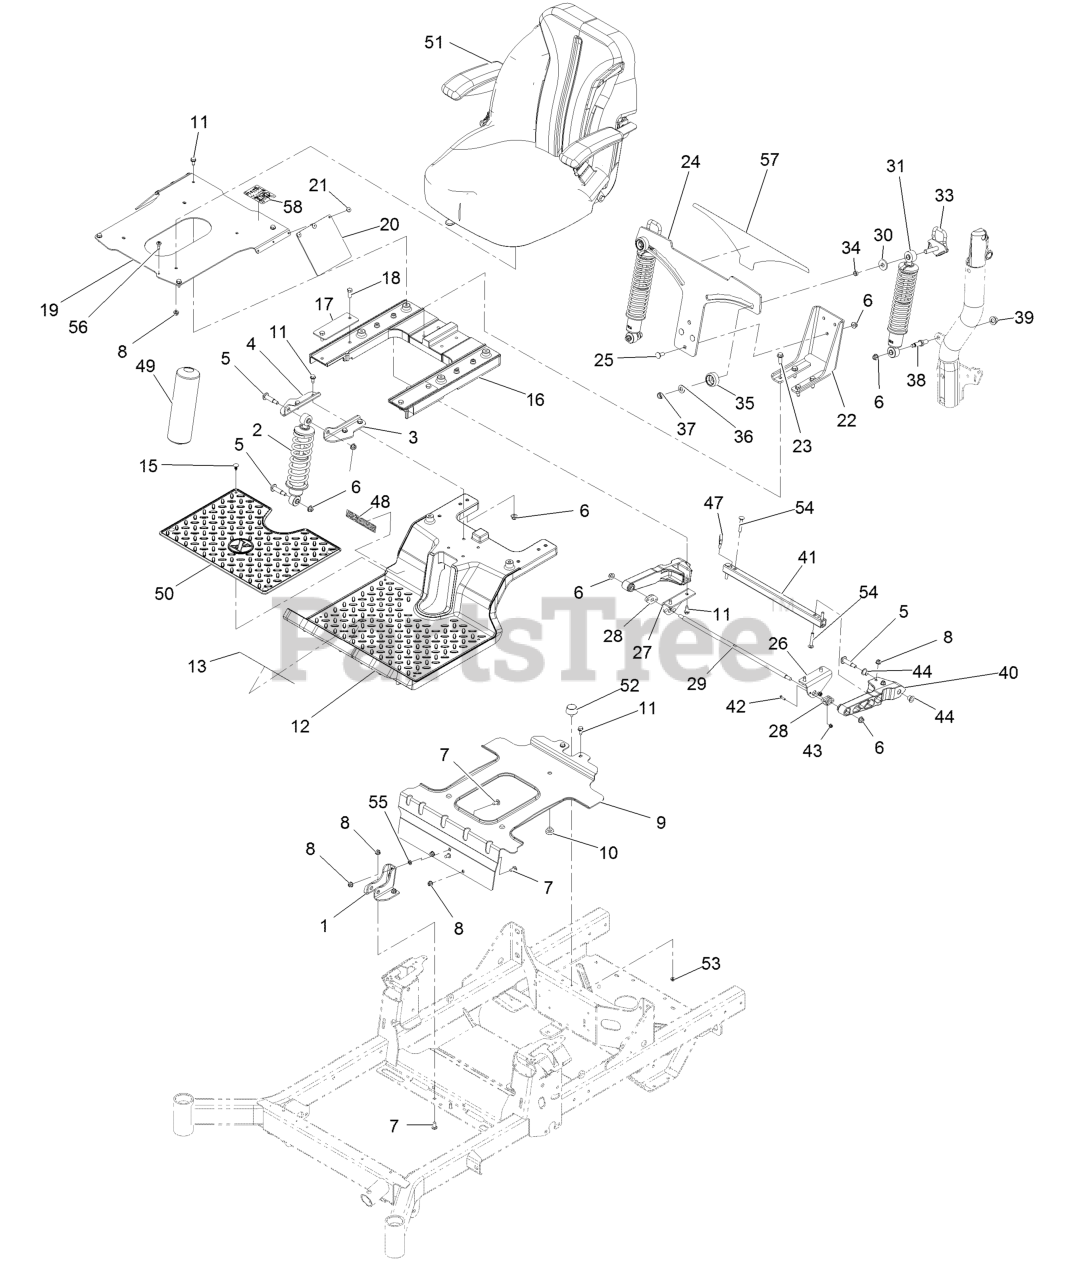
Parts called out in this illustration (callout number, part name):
1	Bracket-Shock, Front Lower
2	Shock/Spring
3	Bracket-Shock Mount, Upper (LH)
4	Bracket-Shock Mount, Upper (RH)
5	Bolt-Shoulder, HWH
6	Nut-Nyloc 3/8-16 Flg
7	Bolt-Carriage 5/16-18 X 3/4 Short Neck
8	Nut-Nyloc 5/16-18 Flg
9	Bracket-Tank
10	Bumper-Seat
11	Screw-HWH 5/16-18 X 3/ Tf
12	Subframe-Front
13	Decal-Danger
15	Plug-Plastic
16	Subframe-Rear
17	Plate-Backer
18	Screw-HH 3/8-16 X 1
19	Plate-Seat
20	Flap-Rubber
21	Rivet-Pop
22	Bracket-Mount, Lower
23	Screw-HWH 3/8-16 X 1 1/4 Taptite
24	Plate-Mounting, Adj Shock
25	Bolt-Carriage 3/8-16 X 1
26	Bracket-Arm, Trailing (LH)
27	Bracket-Arm, Trailing (RH)
28	Bearing-Flange
29	Rod-Pivot
30	Washer-Plastic
31	Shock/Spring ASM
33	Cam Lock ASM
34	Bearing-Sleeve
35	Knob-Lock, Cam
36	Washer-Adjusting
37	Nut-Nyloc 1/2-13 Thin
38	Bolt-Shoulder
39	Nut-Lock 1/2-13
40	Trailing Arm
41	Tube-Arm, Trailing
42	Screw-CARR
44	Bushing-Flange
47	Clamp-Hose
48	Decal-Radius Logo
49	Cover-Shock
50	Floor Mat
51	ASM-Seat Exmark
53	Nut-Nyloc 1/4-20 Flg
54	Bolt-Carriage 3/16-18 X 2
55	Nut-Push
56	Screw-Shoulder
57	Decal-Adjustment, Ride
58	Decal-Aid, Service
